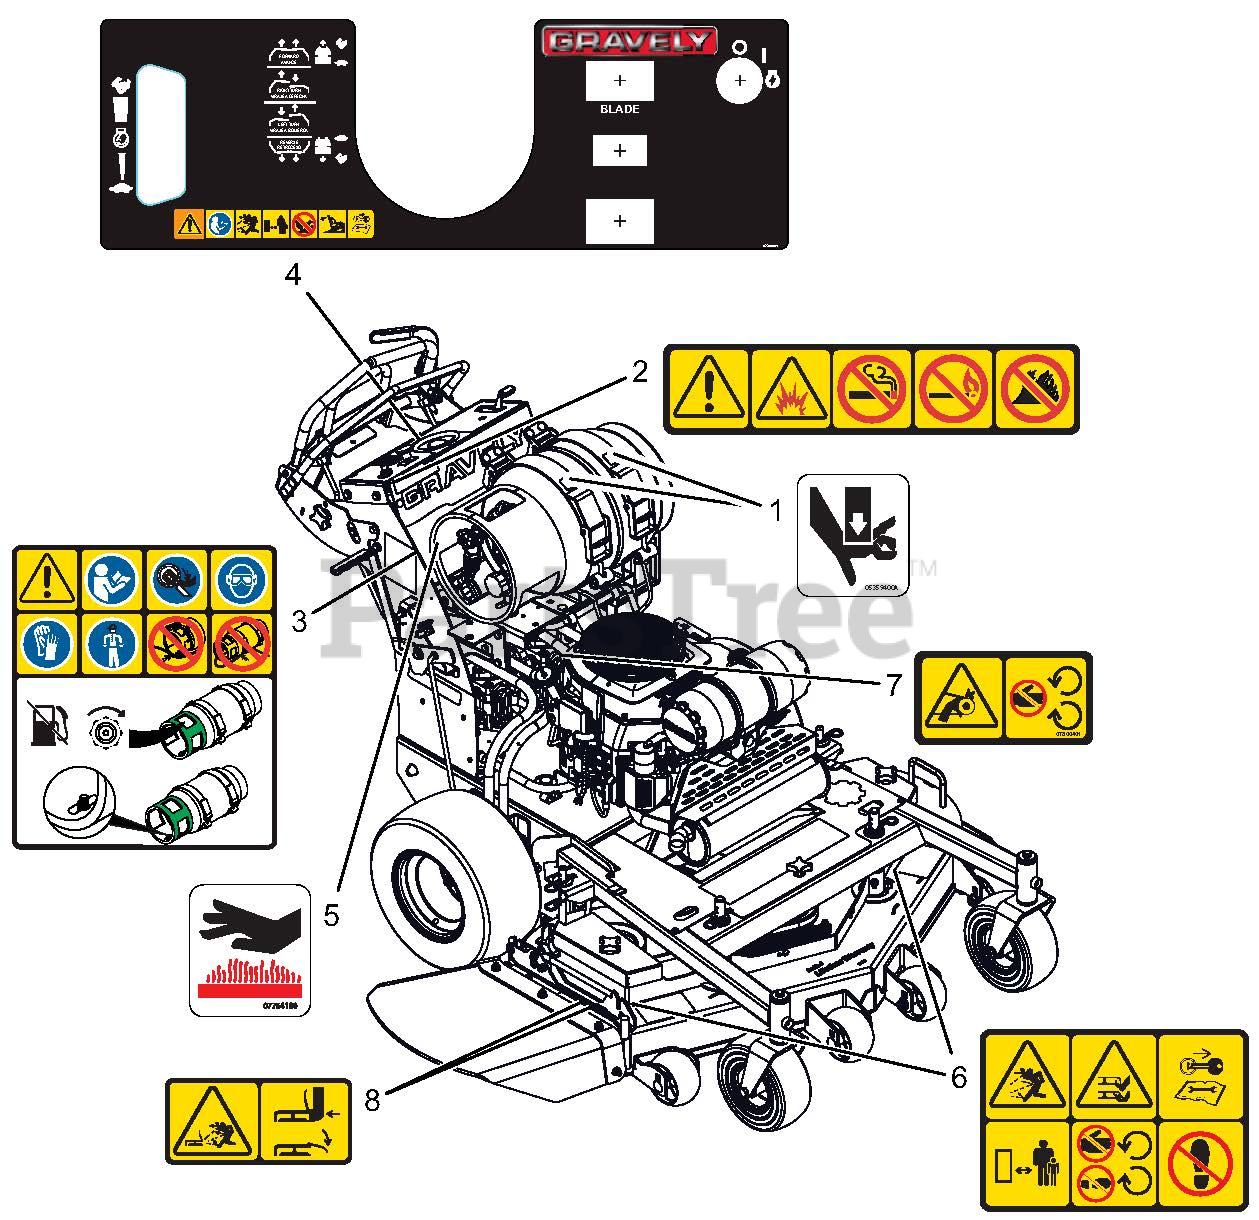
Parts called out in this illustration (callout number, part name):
1	DECAL, PINCH POINT
2	DECAL, SAFETY -LP
3	DECAL, HORIZ MOWER TANKS ONLY
4	DECAL, CONSOLE PS GRV MY13
5	DECAL HOT SURFACE
6	DECAL, SAFETY - MOWER DECK
7	DECAL, SAFETY - GUARDING
8	DECAL, SAFETY - DECK GUARDING
